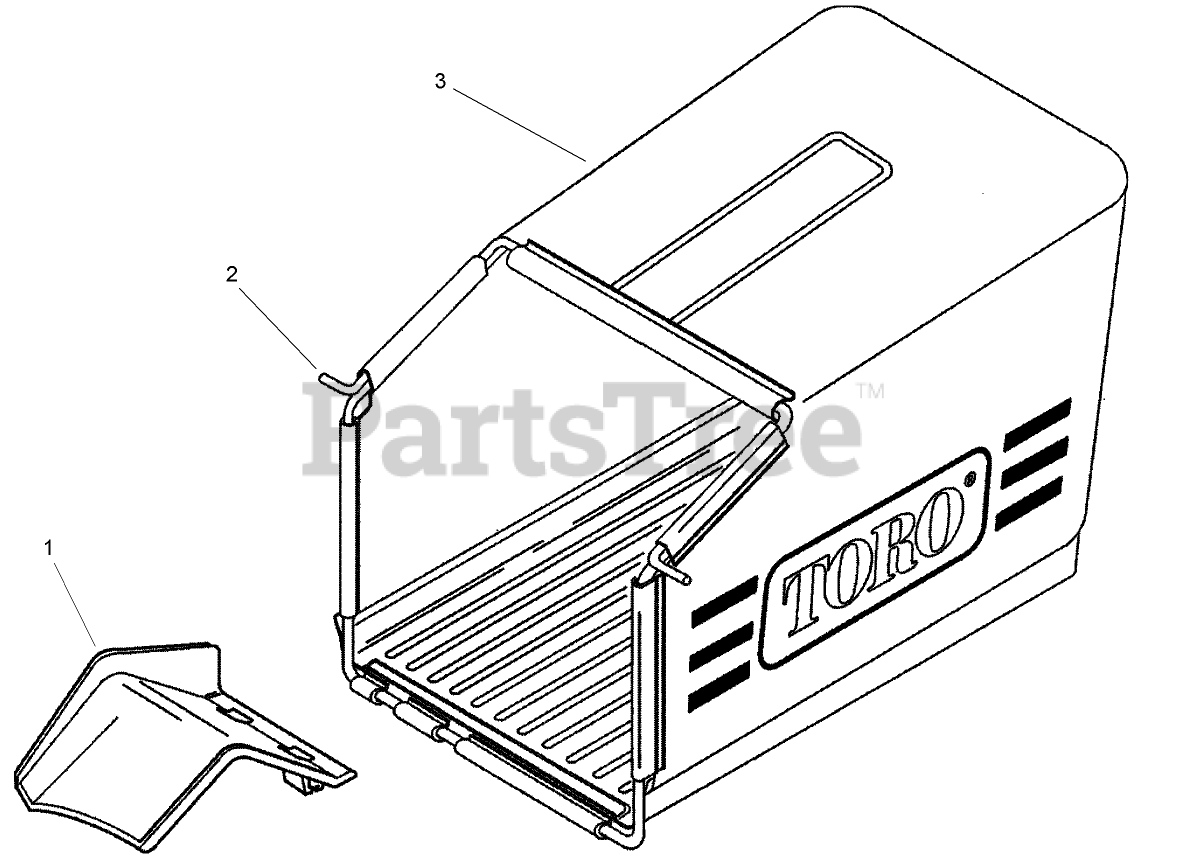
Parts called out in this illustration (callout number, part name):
1	REMOVER-BAG, GRASS
2	FRAME-BAG
3	BAG-GRASS
